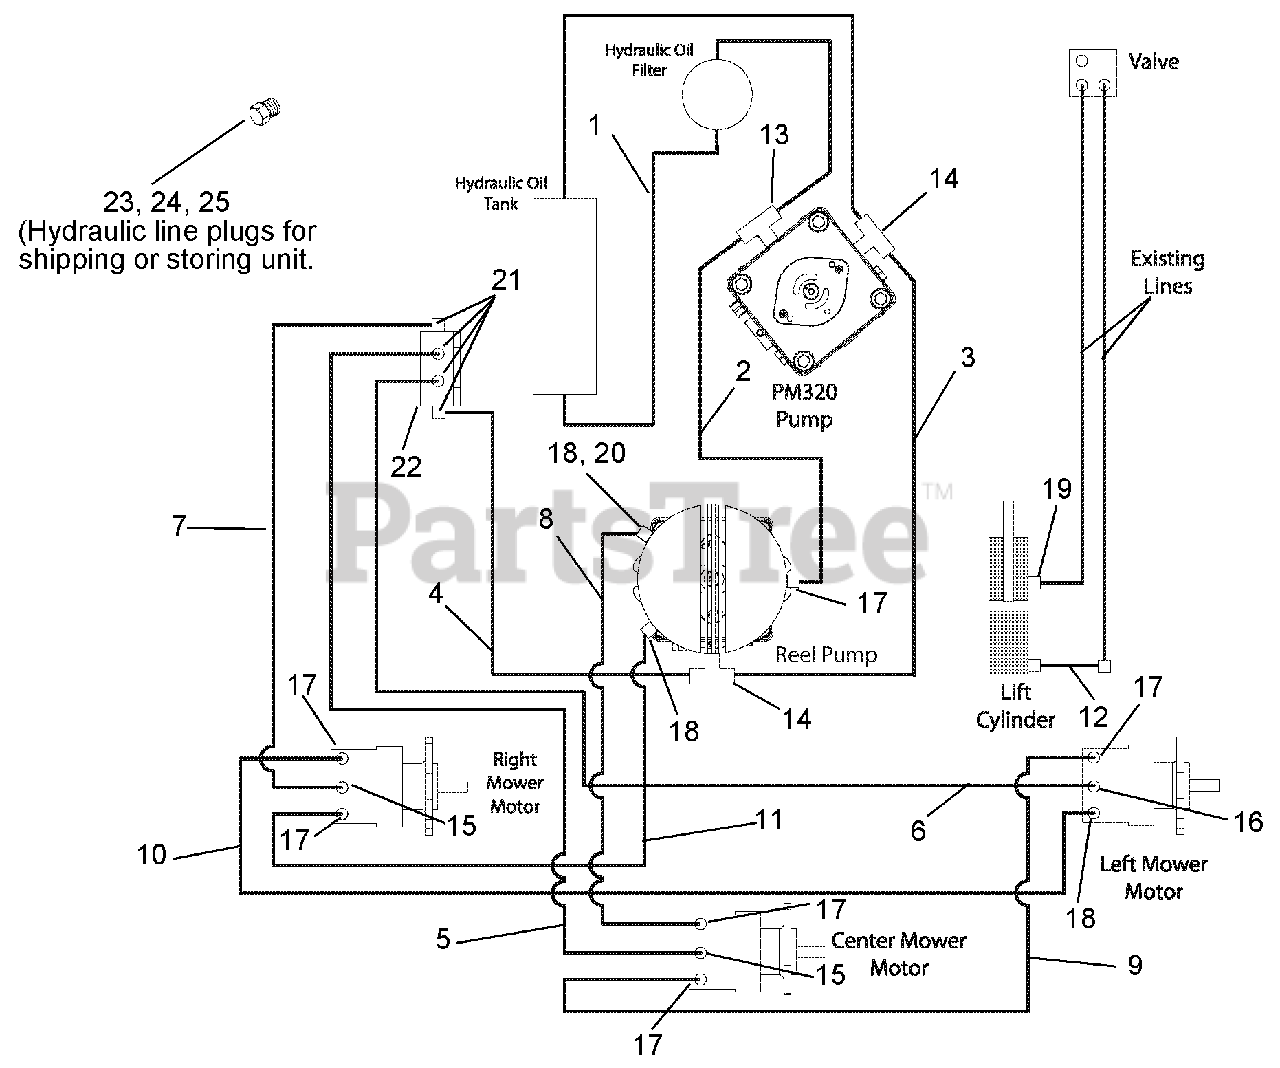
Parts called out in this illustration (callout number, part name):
1	HOSE, 801*JC*J9*8-8-8-18.0"
2	HOSE, 801*JC*J9*8-8-8-20.0"
3	HOSE, 801*JC*JC*6-6-6-21.0"
4	HOSE, AX*JS*J9*6-4-4-15.0" W/Sleeve
5	HOSE, AX*JC*JC*4-4-4-75.0" W/Sleeve
6	HOSE, AX*J7*J9*4-4-4-58.0" (270 deg.) W/Sleeve
7	HOSE, AX*JC*J9*4-4-4-51.0" W/Sleeve
8	HOSE, AX*JC*J9*8-8-8-44.5" W/Sleeve
9	HOSE, AX*JC*JC*8-8-8-82.5" W/Sleeve
10	HOSE, AX*JC*J7*8-8-8-99.0" W/Sleeve
11	HOSE, AX*JC*J9*8-8-8-50.0" W/Sleeve
12	HOSE, AX*JO*JC*4-4-4-7.0" W/Sleeve
13	FITTING, #8 ORF #8ORF #8ORB TEE
14	FITTING, #6 ORF-6ORF-8ORB TEE
15	FITTING, #4 ORF #4ORB 45°
16	FITTING, #4 ORF #4ORB 90°
17	FITTING, #8 ORF #8ORB 90
18	FITTING, #8 ORF #8ORB STRAIGHT
19	FITTING, #4 ORF #6ORB 90° 2
20	ADAPTER, #8 ORF #8ORF FEMALE 90°
21	FITTING, #4 ORF #4 PIPE 90
22	MANIFOLD BLOCK - FOUR PORT 1/4" NPT
23	#8 ORF MALE (I-13/16 PLUG)
24	#6 ORF MALE (I-11/16 PLUG)
25	#4 ORF FEMALE (Y-1/4 CAP)
